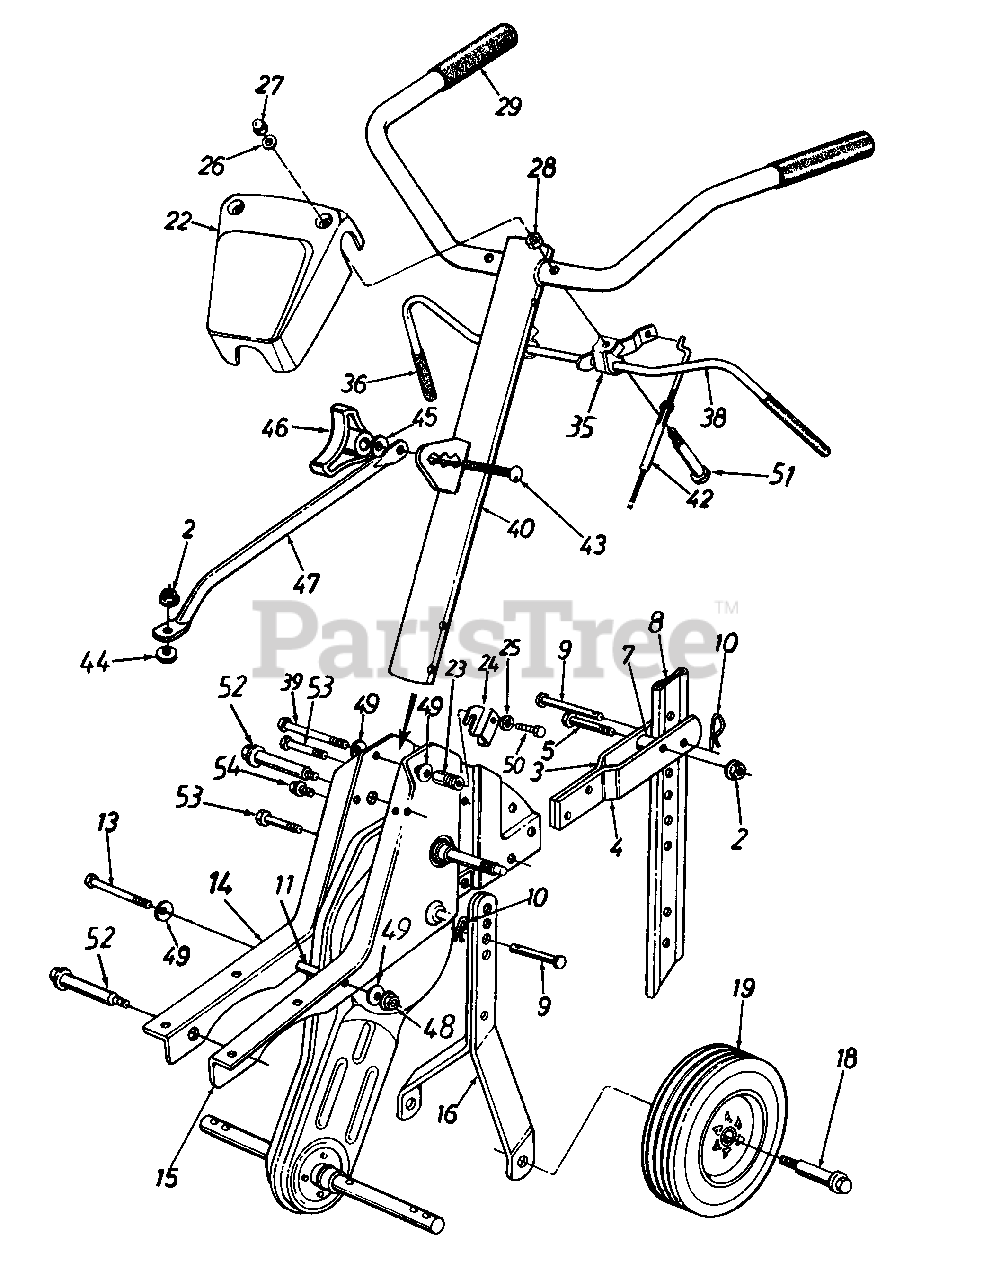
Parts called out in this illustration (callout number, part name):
2	Hex Flange L-Nut 5/16-18 Thd. (Gr. 5)
5	Hex Bolt 5/16-18 x 1.5" Lg.
7	Spacer.32" I.D. x .75" O.D.
9	Clevis Pin .375" I.D. x 1.62" Lg.
10	Internal Cotter Pin
11	Spacer.326" I.D. x .47" O.D.
13	Hex Bolt 5/16-18 x 2.75" Lg.
18	Shld. Bolt .498" Dia. x 1.45" Lg.
19	Wheel Ass'y.
22	Handle Cover
23	Spec. Hex Nut
25	L-Wash. 5/16" I.D.
26	Fl-Wash. .266" I.D. x .625" O.D.
27	Hex L-Stop Nut 1/4-20 Thd.
28	Hex Nut 1/4-20 Thd.
29	Grip - Handle
35	Clutch Handle Holder
36	Grip - Clutch
39	Hex Bolt 5/16-18 x 3" Lg.
43	Carr. Bolt 5/16-18 x 1" Lg.
46	Hand Knob
49	Bell-Wash..345" I.D. x .88" O.D.
50	Hex Bolt 5/16-18 x .75" Lg. (Gr. 5)
51	Hex Bolt 1/4-20 x 2.25" Lg.
52	Shld. Bolt
53	Hex Wash. Hd. TT-Tap Scr. 5/16-18 x .62" Lg.
54	Hex Wash. Hd. TT-Tap Scr. 5/16-18 x 1" Lg.
